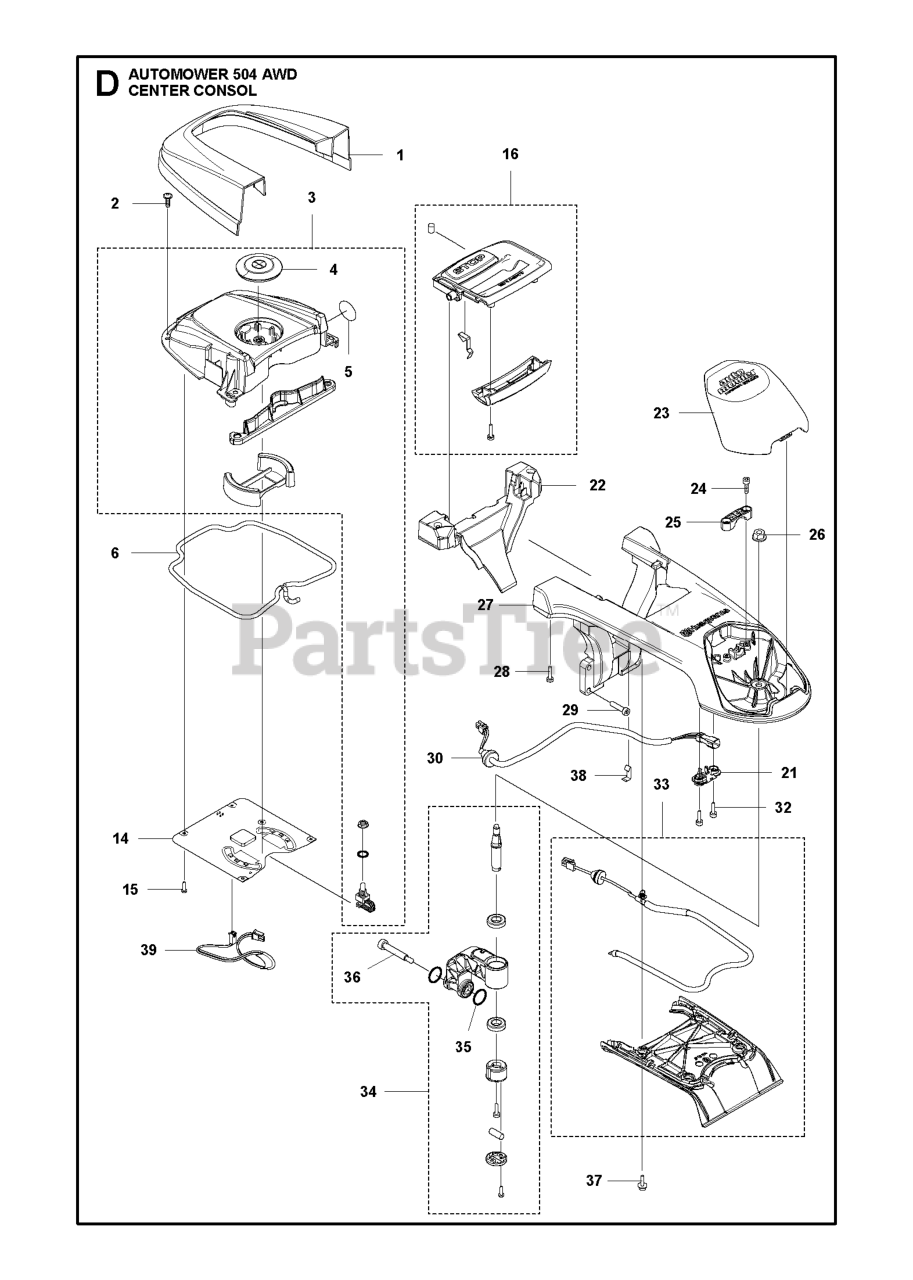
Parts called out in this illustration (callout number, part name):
1	Lids
2	SCREW ITXPANT
4	Knobs
5	AIR FILTER
6	Seals
14	Circuits
15	SCREW CITXPANT
25	Clamps
26	NUT W/ WASHER
28	SCREW ITXSCT PW4.2X18 10.9 ZN
37	SCREW ITXSCM WASHER M5X12 T27
